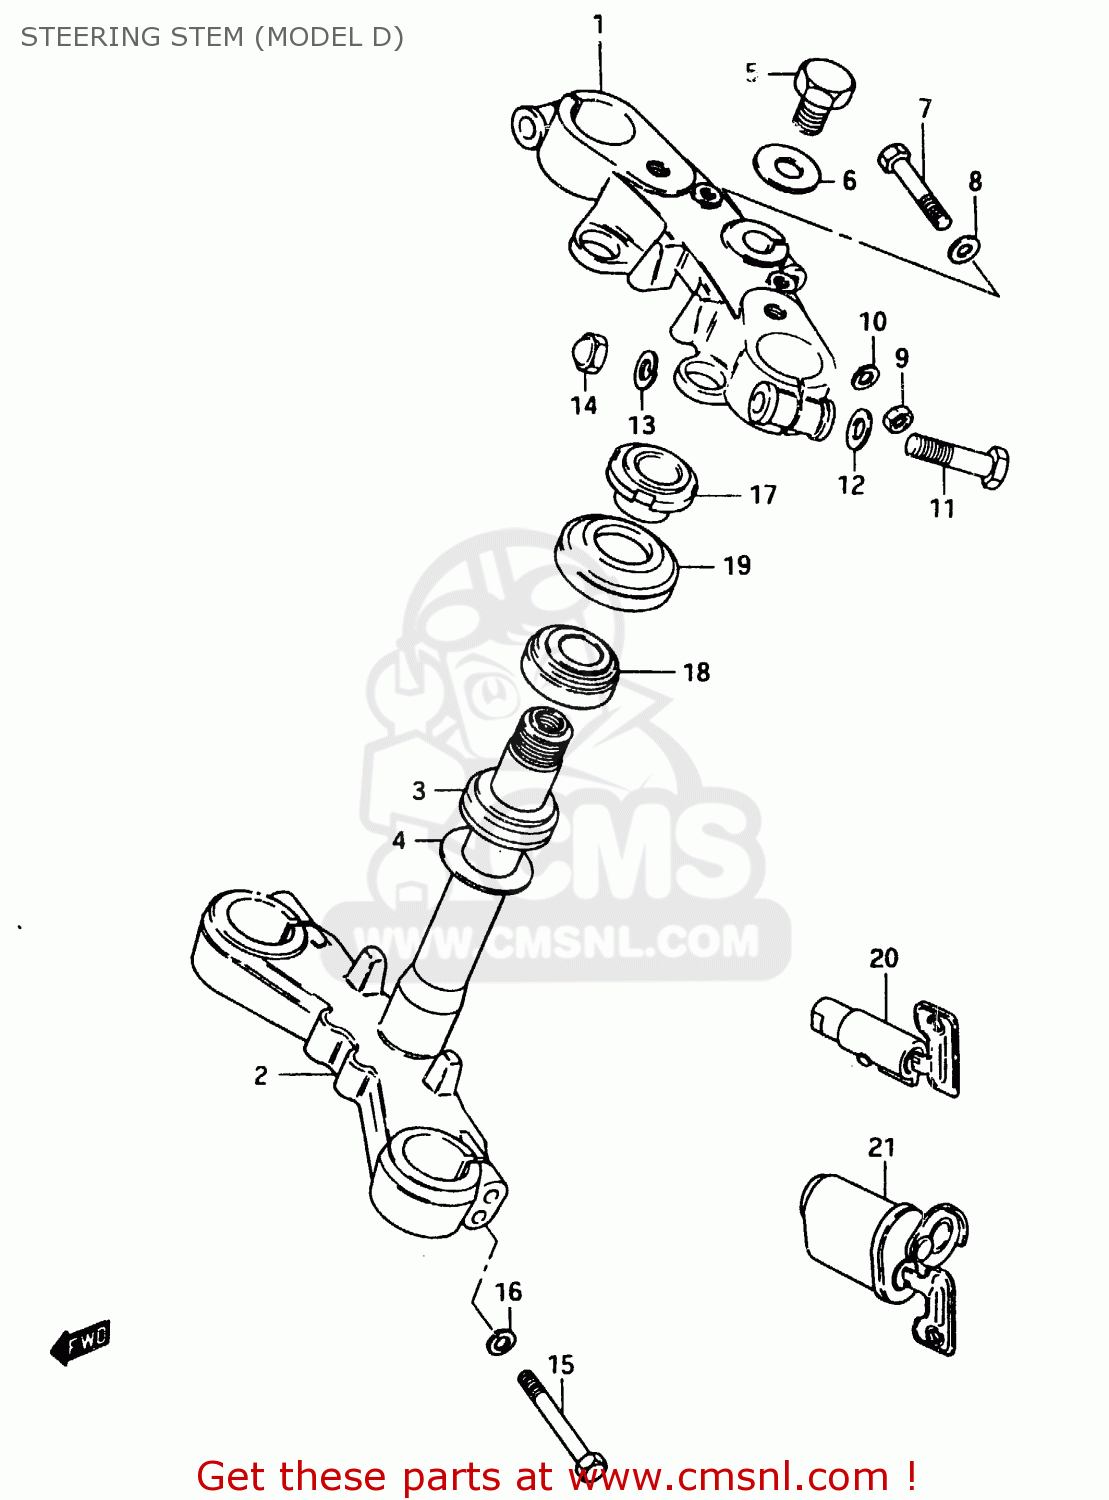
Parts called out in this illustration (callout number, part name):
1	HEAD,STEERING STEM
2	STEM,STEERING
3	BEARING
4	WASHER,THRUST
5	BOLT,STEERING STEM HEAD
6	WASHER
7	BOLT
8	WASHER,8.5X16X
9	NUT 8MM
10	LOCK WASHER
11	BOLT 10X55
12	WASHER 10MM
13	LOCK WASHER
14	NUT
15	BOLT 8X40
16	LOCK WASHER
17	NUT,STEERING STEM
18	TAPER,ROLLER BEARING
19	DUST SEAL,STEERING UPR
20	LOCK ASSEMBLY,STEERING (NEI
21	LOCK ASSY, STEERING (NEIMAN TYPE EXECUTE
